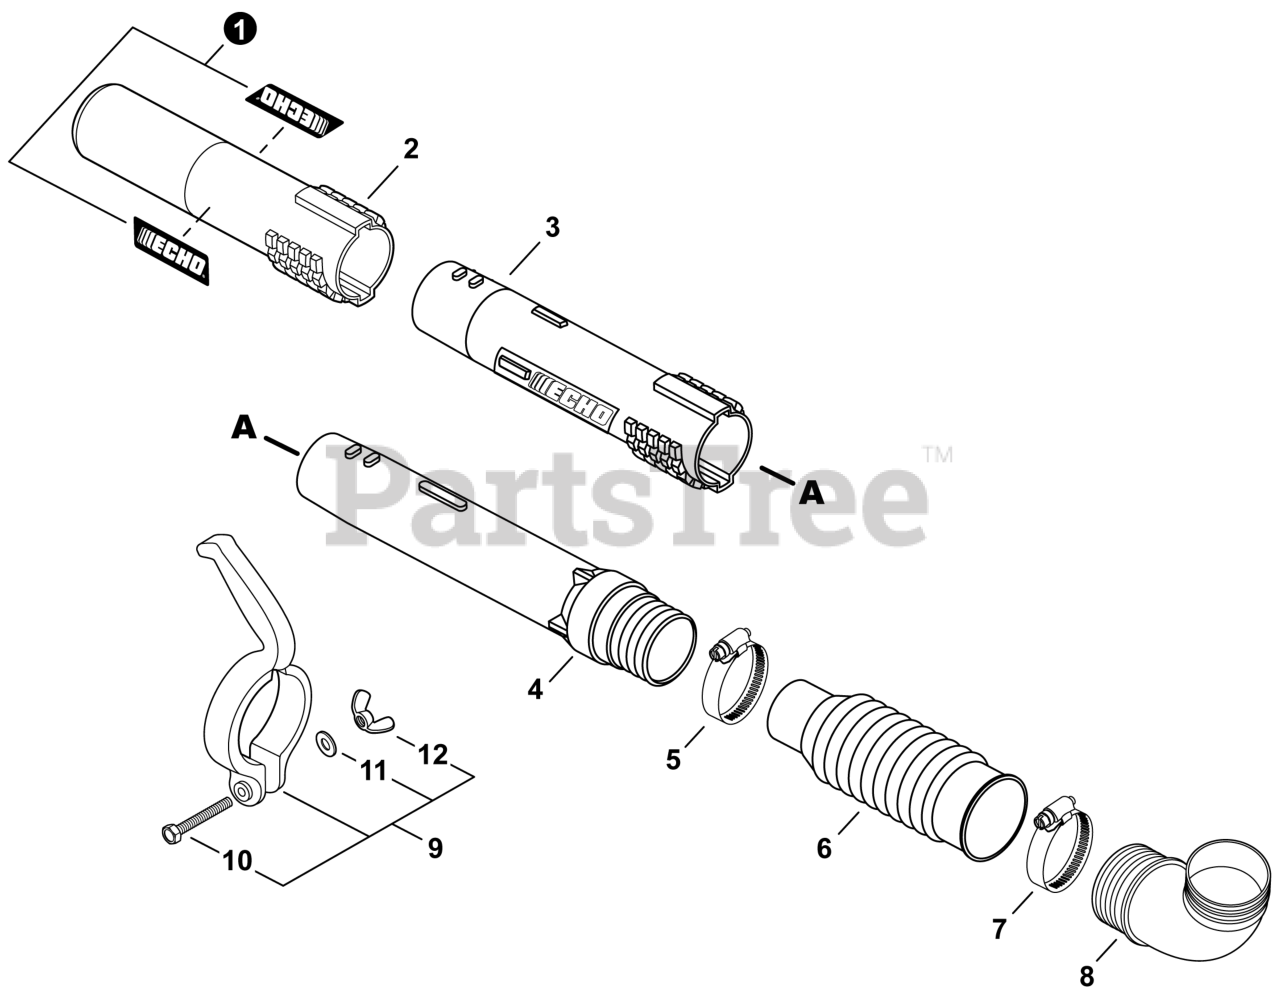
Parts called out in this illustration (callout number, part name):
1	LABEL - ECHO
2	TUBE, BLOWER - NOZZLE
3	TUBE, BLOWER - STRAIGHT
4	TUBE, BLOWER - SWIVEL
5	CLAMP - BAND 58.7 MM / 82.5 MM
6	TUBE, BLOWER - FLEXIBLE
7	CLAMP - BAND 78 MM / 103 MM
8	TUBE, BLOWER - ELBOW
9	HANDLE SET, FRONT
10	BOLT 6x45
11	WASHER 6.5x11.5x0.8
12	NUT, WING 6
